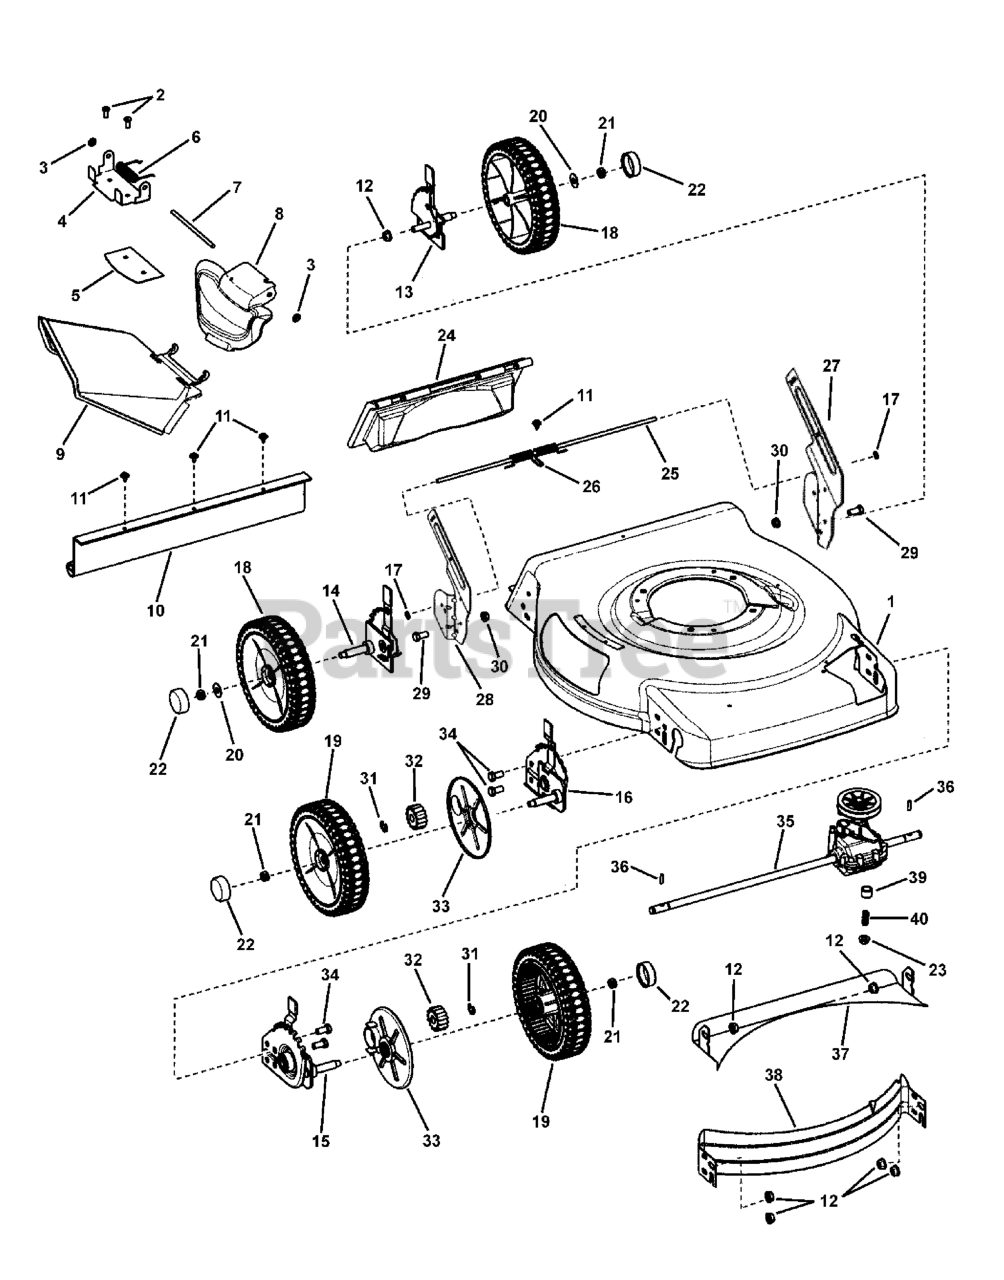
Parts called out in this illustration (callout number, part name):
1	DECK, 22" Walk, 3-N-1
2	SCREW, Pan Head, Self Tap, Torx, 1/4-20 x 1/2
3	PUSHNUT, 1/4
4	BRACKET, Chute
5	PLATE, Mulch
6	SPRING, Chute, Torsion
7	ROD, Chute Pivot
8	COVER, Mulch
9	SIDE CHUTE
10	GUARD, Rear
11	SCREW, Hex Washer, Self Tap, Sems, #10-24 x 1/2
12	NUT, 3/8-16 Hex Flange Lock, GR 5
13	ASSEMBLY, Height-of-Cut, Left Rear, 7 Position
14	ASSEMBLY, Height-of-Cut, Right Rear, 7 Position
15	ASSEMBLY, Height-of-Cut, Left Front, Self-Prop, 7 Position
16	ASSEMBLY, Height-of-Cut, Right Front, Self-Prop, 7 Position
17	CAP, Retainer
18	WHEEL, 8 x 2, Idle
19	WHEEL, 8 x 2, Drive
20	WASHER, Flat, 3/8 ID x 1 OD
21	NUT, Hex Centerlock, 3/8-16
23	NUT, Hex Flange Lock, 5/16-18
24	DOOR, Rear Discharge
25	ROD, Pivot, Rear Door
26	SPRING, Torsion, Rear Door
27	BRACKET, Lower Handle, Right
28	BRACKET, Lower Handle, Left
29	BOLT, Hex Flange Lock, 5/16-18 x 5/8
30	NUT, Flange Lock, 5/16-18
31	RING, External Retaining
32	GEAR, Pinion
33	SHIELD, Dust
34	CAPSCREW, Hex Head, 3/8-16 x 3/4, GR 5
35	TRANSMISSION, Single Speed, Front Wheel Drive
36	DRIVE PIN
37	BAFFLE, Rear
38	BAFFLE, Front
39	SPACER, Engine
40	SPRING, Compression
